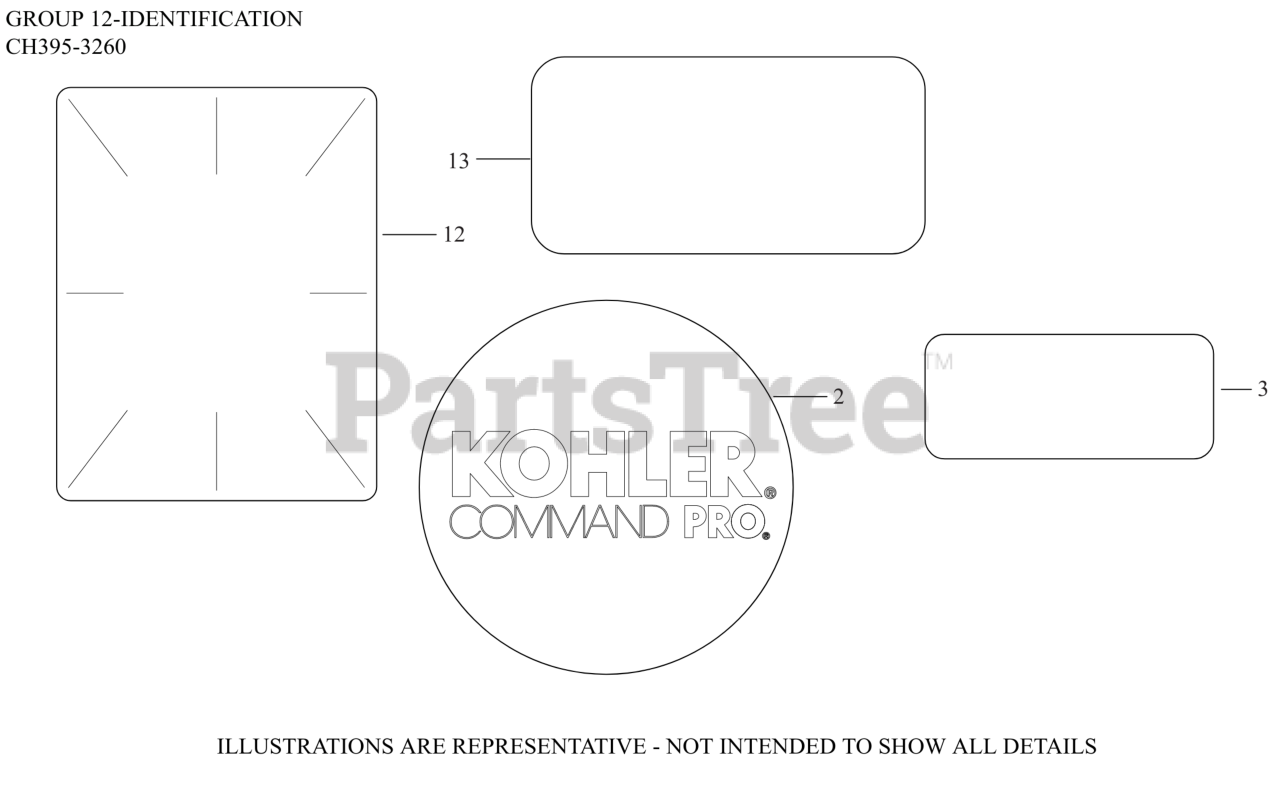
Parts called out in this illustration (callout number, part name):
2	LABEL, RECOIL 75MM
3	LABEL, CANADIAN COMPLIANCE
12	LABEL, CLEAR LAMINATION
13	LABEL, MAINTENANCE (CKY)
